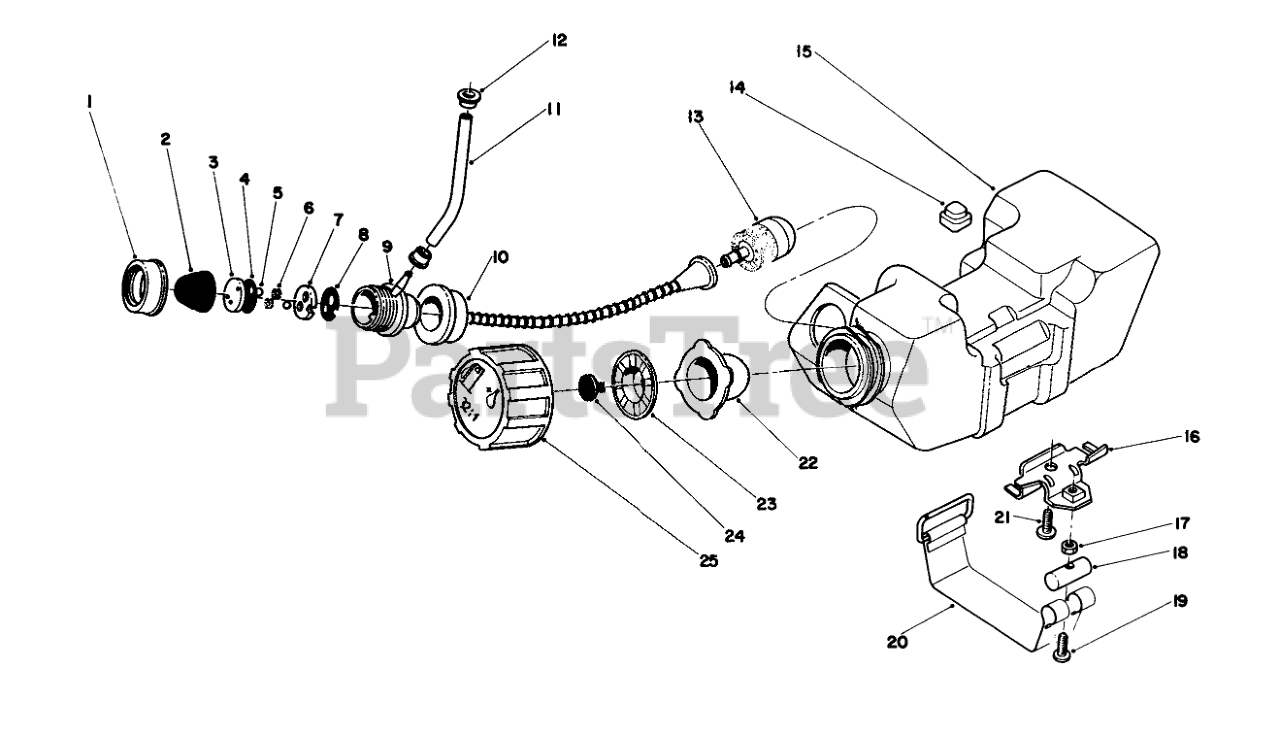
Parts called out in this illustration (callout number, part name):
1	PUMP CAP
3	SEAT VALVE
4	GASKET
6	SPONGE
7	SEAT VALVE
8	GASKET
9	Pump-Primer (Incl. Ref. #2-8)
10	HOSE, SUCTION
11	Tube-Fuel
13	FUEL FILTER
15	Fuel Tank Assembly (Incl. Ref. #1-10, 13, 21-24)
16	HANGER, TANK
19	Screw
20	BAND, TANK
21	Screw
22	GASKET - PACKING
23	HOLDER
24	BREATHER VALVE
25	TANK CAP
